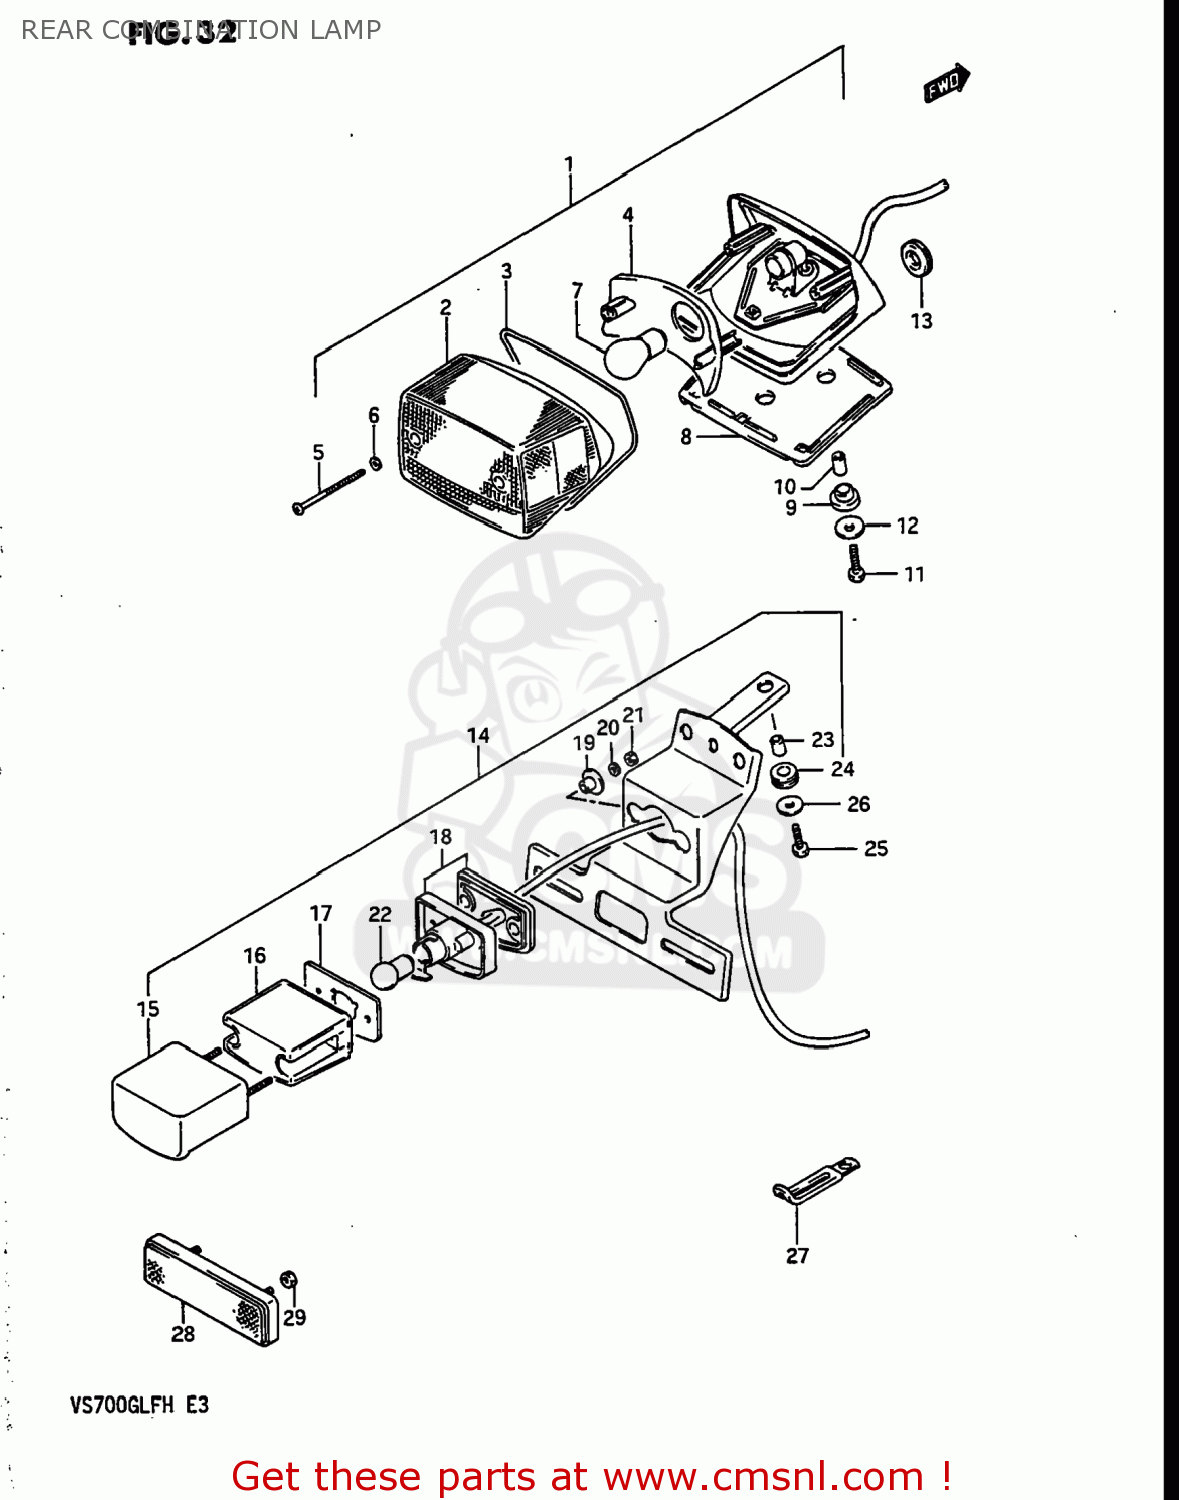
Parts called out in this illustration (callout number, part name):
1	LAMP ASSEMBLY,REAR COMBINATION
2	LENS
3	GASKET (NAS)
4	REFLECTOR
5	SCREW
6	GASKET (NAS)
7	BULB(12V23/8W,TOKAI DENSO)
8	CUSHION
9	CUSHION
10	SPACER
11	BOLT
12	WASHER
13	GROMMET
14	LAMP ASSY,LICENSE
15	COVER,LICENSE LAMP
16	LENS
17	GASKET,LICENSE LAMP (NAS)
18	HOUSING,LICENSE LAMP
19	SPACER
20	WASHER,LOCK 4M
21	NUT
22	BULB
23	SPACER
24	CUSHION
25	BOLT,M6X1X20
26	WASHER
27	CLAMP L:35
28	REFLEX REFLECTOR ASSY,RR
29	NUT
